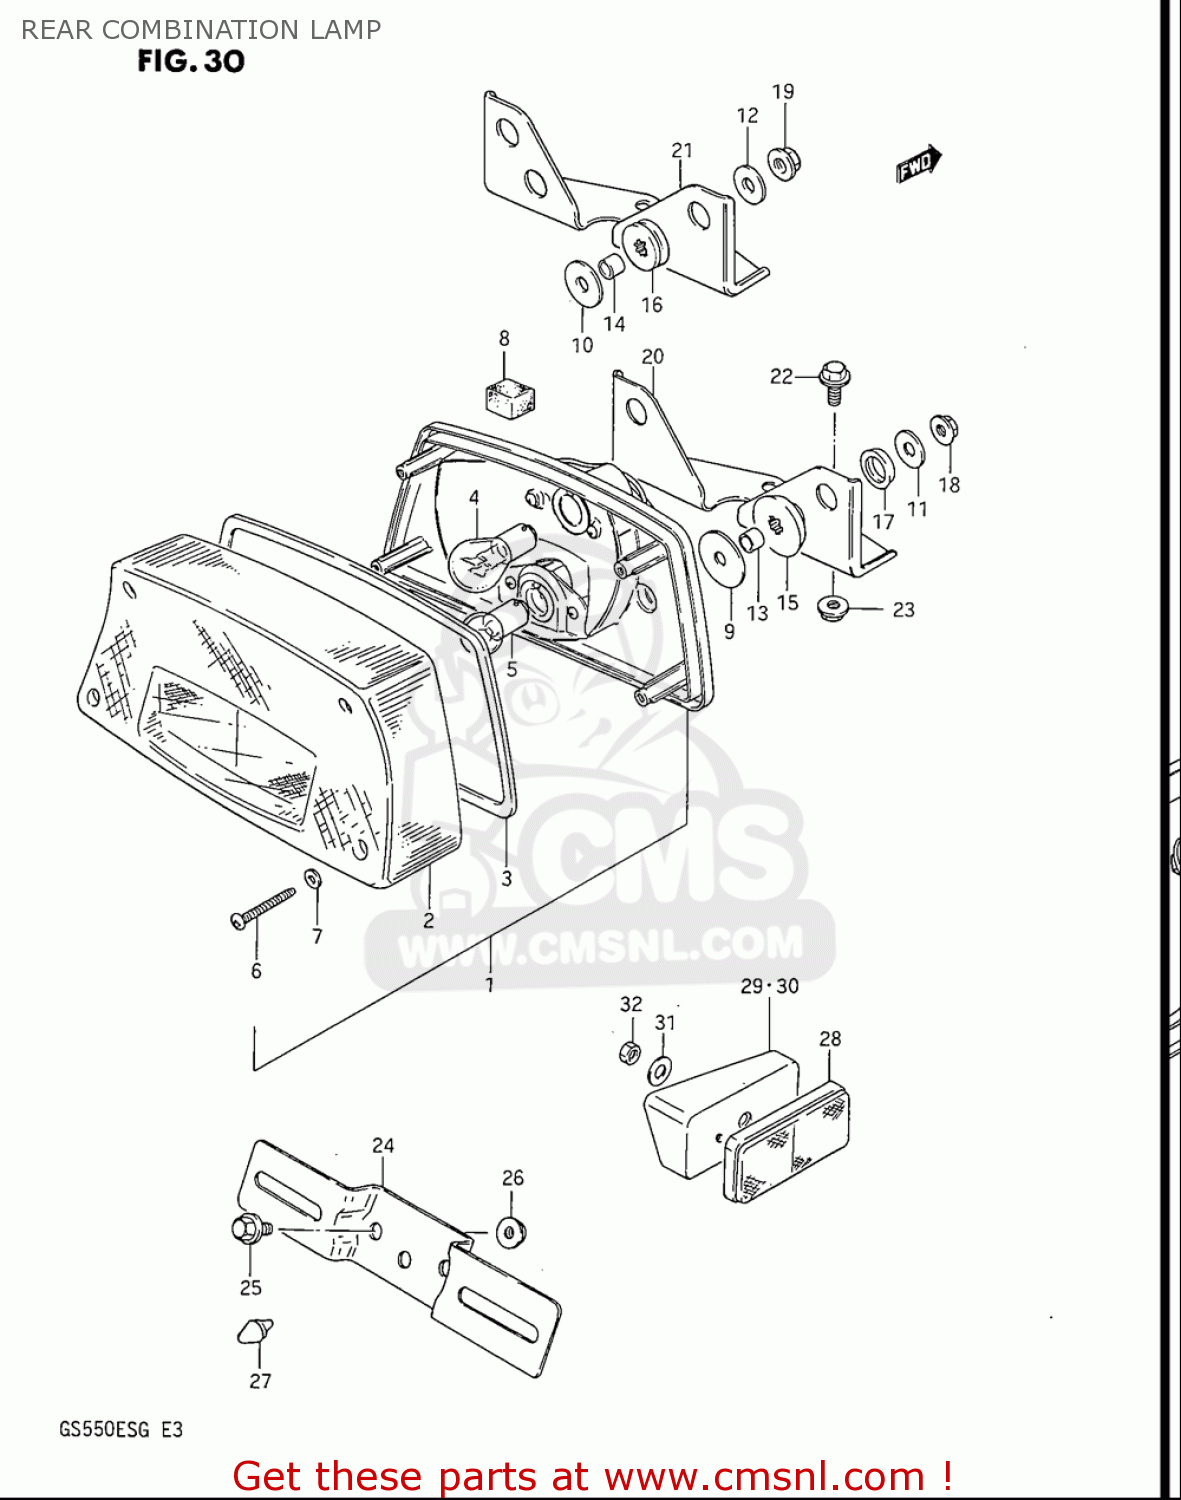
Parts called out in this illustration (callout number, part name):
4	BULB(12V23/8W,TOKAI DENSO)
5	BULB(12V8W)
6	SCREW
7	GASKET (NAS)
8	CUSHION
9	WASHER(6.5X30X1.2)
10	WASHER(6.5X20X1.6)
11	WASHER(6.5X22X1.6)
13	SPACER (6.8X10X11.5)
14	SPACER
15	CUSHION
16	CUSHION,RR COMBINATION
17	CUSHION
18	NUT
20	BRACKET,REAR COMBINATION LAMP
21	BRACKET,REAR COMBINATION LAMP
23	NUT
24	BRACKET,LICENSE PLATE
25	BOLT
26	NUT
27	CUSHION
28	REFLECTOR,REFLEX
31	WASHER(5.2X16X1)
32	NUT
